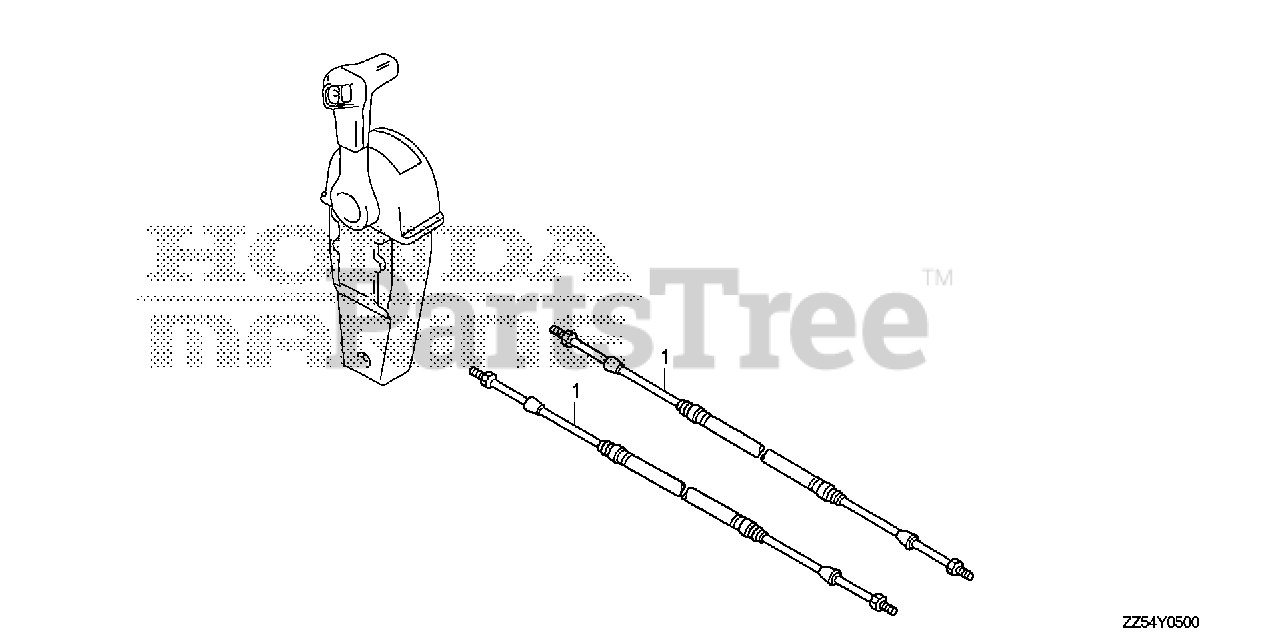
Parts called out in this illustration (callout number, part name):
1	CABLE, REMOTE CONTROL (10') (LOW FRICTION)
1	CABLE ASSY., PUSH-PULL (33C-5FT)
1	CABLE, REMOTE CONTROL (11') (LOW FRICTION)
1	CABLE ASSY., PUSH-PULL (33C-6FT)
1	CABLE, REMOTE CONTROL (12') (LOW FRICTION)
1	CABLE ASSY., PUSH-PULL (33C-7FT)
1	CABLE, REMOTE CONTROL (13') (LOW FRICTION)
1	CABLE ASSY., PUSH-PULL (33C-8FT)
1	CABLE, REMOTE CONTROL (14') (LOW FRICTION)
1	CABLE ASSY., PUSH-PULL (33C-9FT)
1	CABLE, REMOTE CONTROL (15') (LOW FRICTION)
1	CABLE ASSY., PUSH-PULL (33C-10FT)
1	CABLE, REMOTE CONTROL (16') (LOW FRICTION) (NOT AVAILABLE)
1	CABLE ASSY., PUSH-PULL (33C-11FT)
1	CABLE, REMOTE CONTROL (17') (LOW FRICTION)
1	CABLE ASSY., PUSH-PULL (33C-12FT)
1	CABLE, REMOTE CONTROL (18') (LOW FRICTION) (NOT AVAILABLE)
1	CABLE ASSY., PUSH-PULL (33C-13FT)
1	CABLE, REMOTE CONTROL (19') (LOW FRICTION)
1	CABLE ASSY., PUSH-PULL (33C-14FT)
1	CABLE, REMOTE CONTROL (20') (LOW FRICTION) (NOT AVAILABLE)
1	CABLE ASSY., PUSH-PULL (33C-15FT)
1	CABLE, REMOTE CONTROL (21') (LOW FRICTION)
1	CABLE ASSY., PUSH-PULL (33C-16FT)
1	CABLE, REMOTE CONTROL (22') (LOW FRICTION) (NOT AVAILABLE)
1	CABLE ASSY., PUSH-PULL (33C-17FT)
1	CABLE, REMOTE CONTROL (23') (LOW FRICTION)
1	CABLE ASSY., PUSH-PULL (33C-18FT)
1	CABLE, REMOTE CONTROL (24') (LOW FRICTION) (NOT AVAILABLE)
1	CABLE ASSY., PUSH-PULL (33C-19FT)
1	CABLE, REMOTE CONTROL (25') (LOW FRICTION)
1	CABLE ASSY., PUSH-PULL (33C-20FT)
1	CABLE, REMOTE CONTROL (26') (LOW FRICTION)
1	CABLE ASSY., PUSH-PULL (33C-21FT)
1	CABLE, REMOTE CONTROL (27') (LOW FRICTION)
1	CABLE ASSY., PUSH-PULL (33C-22FT)
1	CABLE, REMOTE CONTROL (28') (LOW FRICTION) (NOT AVAILABLE)
1	CABLE ASSY., PUSH-PULL (33C-23FT)
1	CABLE, REMOTE CONTROL (29') (LOW FRICTION)
1	CABLE ASSY., PUSH-PULL (33C-24FT)
1	CABLE, REMOTE CONTROL (30') (LOW FRICTION) (NOT AVAILABLE)
1	CABLE ASSY., PUSH-PULL (33C-25FT)
1	CABLE, REMOTE CONTROL (31') (LOW FRICTION)
1	CABLE ASSY., PUSH-PULL (33C-26FT)
1	CABLE, REMOTE CONTROL (32') (LOW FRICTION) (NOT AVAILABLE)
1	CABLE ASSY., PUSH-PULL (33C-27FT)
1	CABLE, REMOTE CONTROL (33') (LOW FRICTION)
1	CABLE ASSY., PUSH-PULL (33C-28FT)
1	CABLE, REMOTE CONTROL (34') (LOW FRICTION) (NOT AVAILABLE)
1	CABLE ASSY., PUSH-PULL (33C-29FT)
1	CABLE, REMOTE CONTROL (35') (LOW FRICTION)
1	CABLE ASSY., PUSH-PULL (33C-30FT)
1	CABLE ASSY., PUSH-PULL (33C-31FT)
1	CABLE ASSY., PUSH-PULL (33C-32FT)
